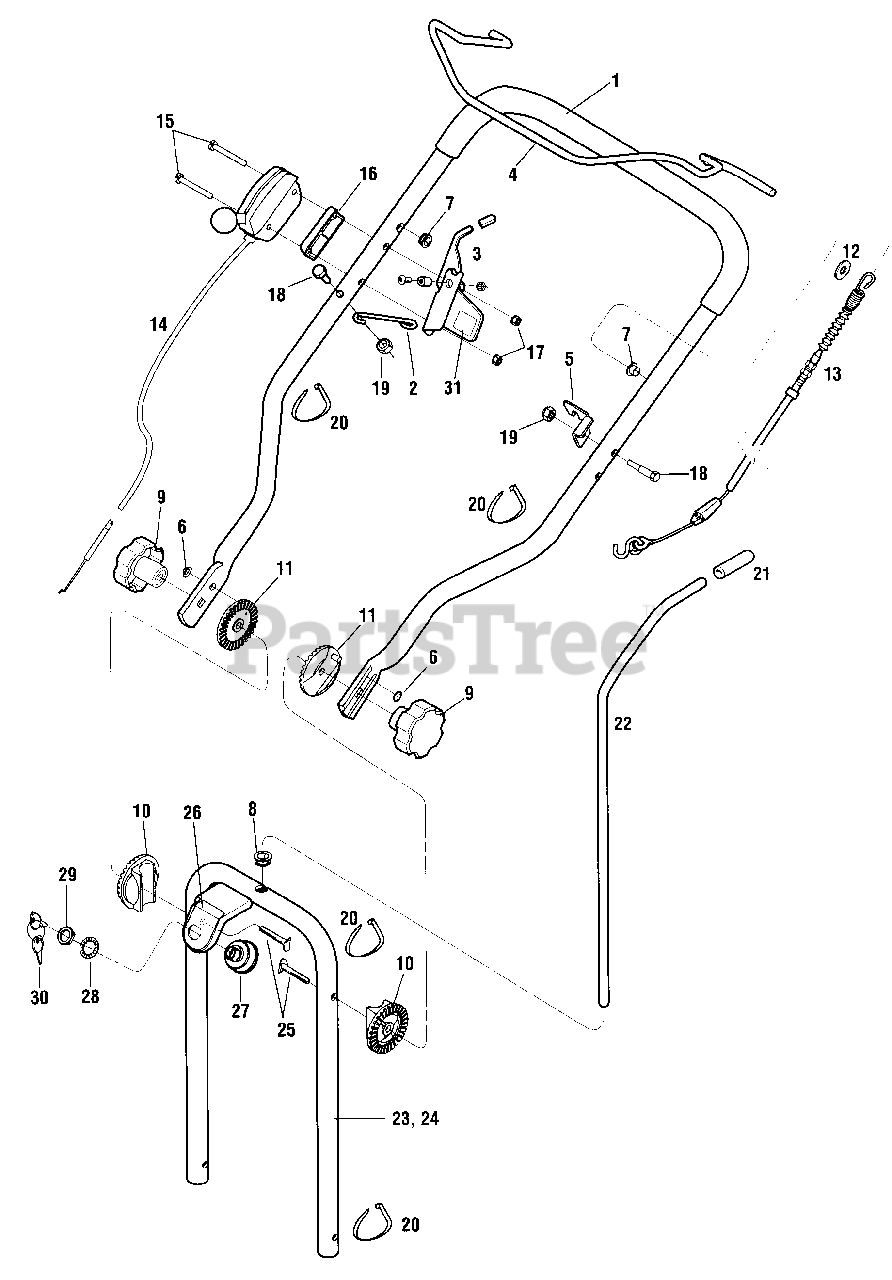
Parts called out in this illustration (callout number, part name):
1	Upper Handlebar w/Sleeve
2	Rope Guide
3	Bail Stop/Latch Assembly
5	Cable Bracket
6	Push-on Retainer
7	Nyliner Bushing
8	Nyliner Bushing
9	Adjusting Knob
10	Inside Hndlbr. Adj. Quadrant
11	Outside Hndlbr. Adj. Quadrant
12	Flat Washer, 5/16
13	Control Cable
14	Throttle Cable
15	Screw, 10-24 x 2
17	Lock Nut, 10-24
18	Hex Hd Screw, 1/4 20 x 1-1/8
19	Top Lock Nut, 1/4-20
20	Cable Tie
21	Steering Rod Grip
22	Upper Steering Rod
23	Lower Handlebar
24	Lower Handlebar
25	Curved Head Bolt, 5/16-18 x 2
26	Decal-Keyswitch
27	Ignition Switch
28	Lockwasher, 5/8
29	Hex Nut, 5/8-32
30	Ignition Key
31	Bail Latch Decal
